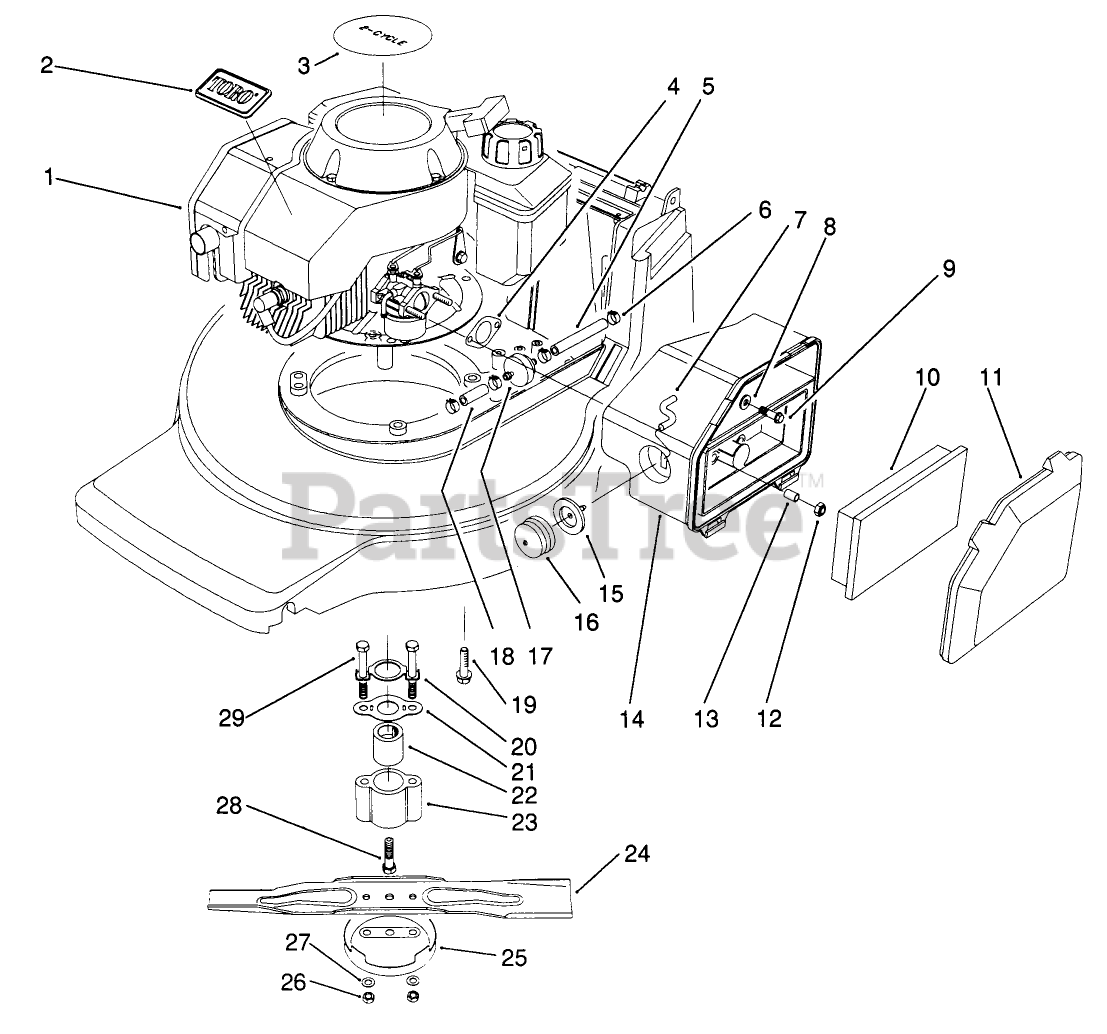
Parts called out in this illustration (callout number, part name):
1	ENGINE 121CC INT'L 2CYC
2	TORO LOGO PLT
3	DECAL- 2 CYC RECOIL
4	GASKET-AIR CLEANER
5	HOSE-FUEL
6	CLAMP-FUEL LINE
7	HOSE-PRIMER
8	WASHER-FLAT
9	SCREW-HH
10	ELEMENT-AIR CLEANER
11	COVER-AIR CLEANER
13	SPACER
14	BODY-AIR CLEANER
15	BODY-PRIMER
16	BULB-PRIMER
17	FILTER-FUEL
18	HOSE-FUEL
19	SCREW-HHF, WHIZ
20	BLADE RETAINER BRKT
21	SPRING FRICTION
23	RETAINER
24	Blade-48cm
25	CUP-SCALP, ANTI
26	NUT-LOCK
27	WASHER
28	SCREW - CRANKSHAFT
29	SCREW - BLADE
